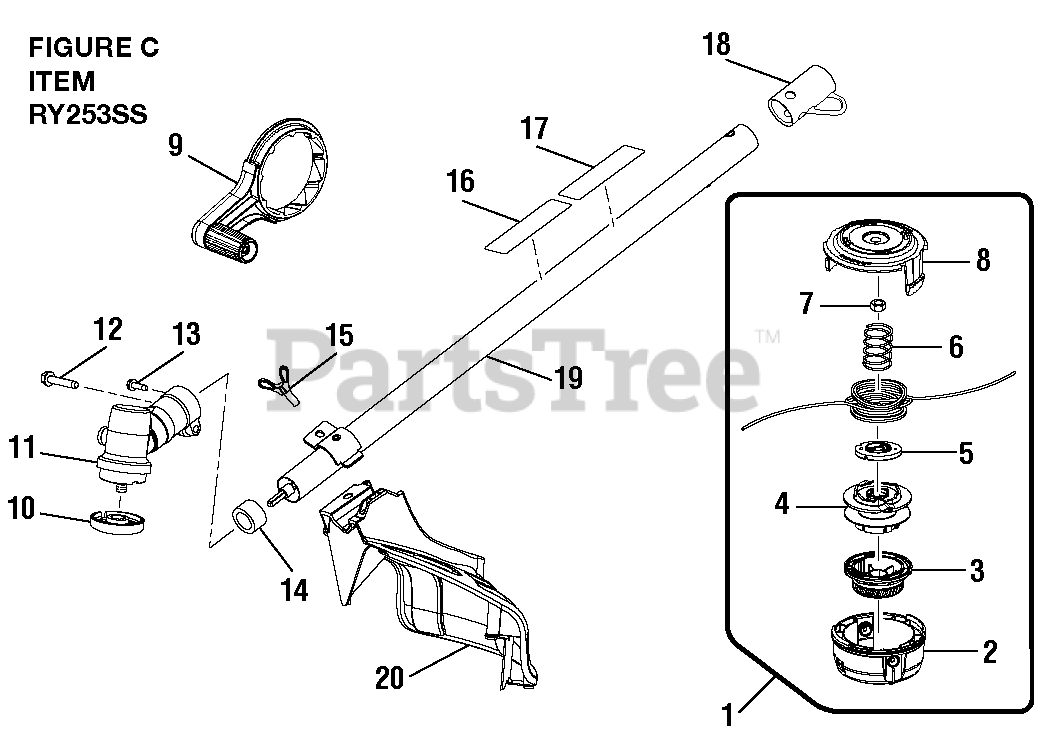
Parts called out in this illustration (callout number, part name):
1	Trimmer Head Assembly (.095)
2	Lower Housing
3	Bump Knob (Green)
5	String Guide
6	Compression Spring
7	Hex Nut (M8, L.H. Thread)
8	Upper Housing
9	Crank Handle Assembly
10	Flanged Washer
11	Gear Case Assembly
12	Screw (1/4-20 x 1-1/4 in., Hex Washer Hd. S.T.)
13	Screw (10-24 x 5/8 in., Hex Washer Hd. S.T.)
15	Wing Screw (1/4-20 x 7/8 in.)
16	Expand-it Label
17	Warning Icon Label
18	Storage Hanger Cap
19	Straight Shaft Assembly
20	Grass Deflector Assembly
